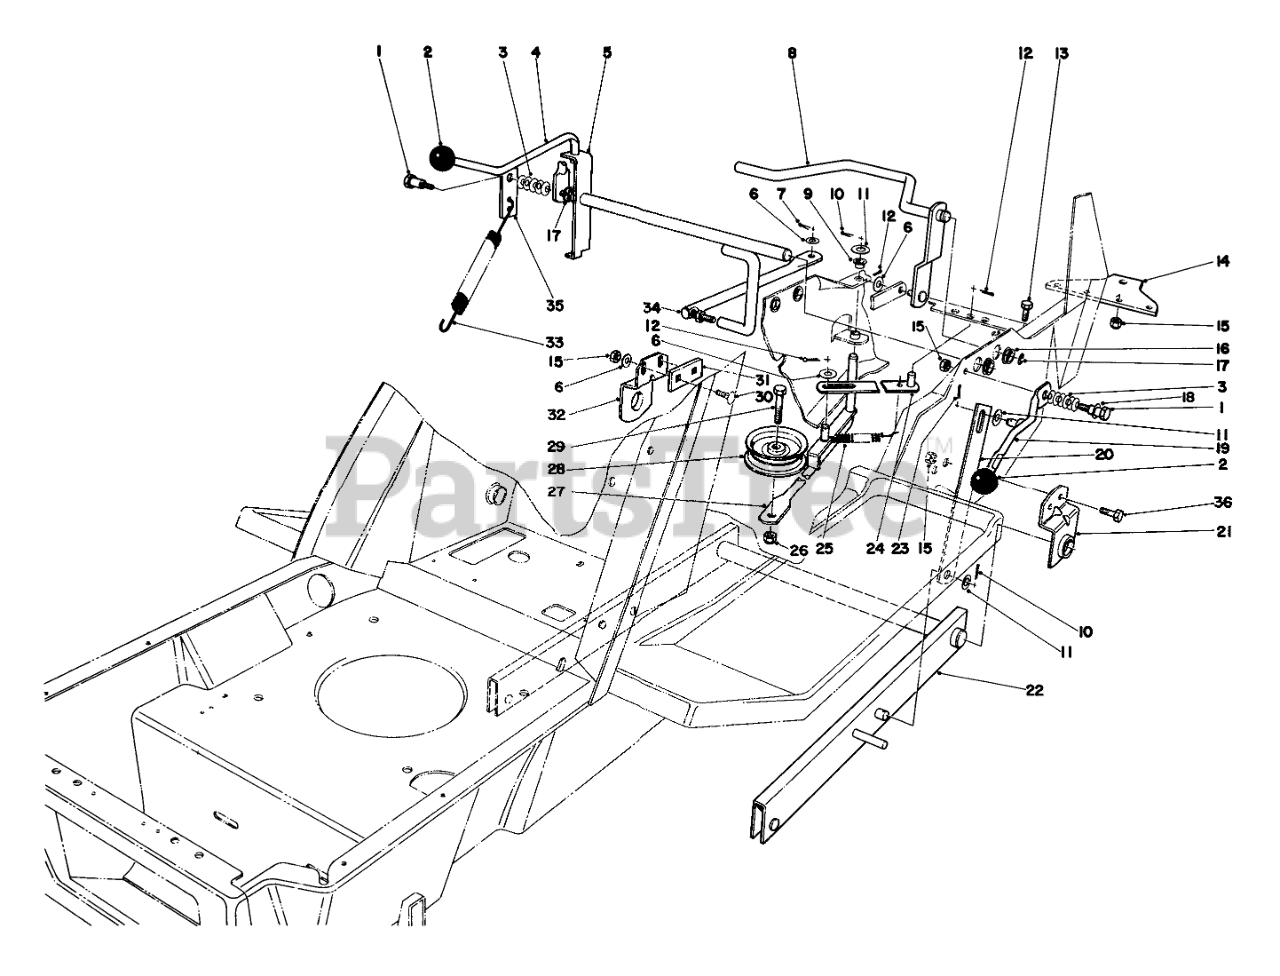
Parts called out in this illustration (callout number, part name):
1	BOLT-SHOULDER
3	WASHER-BELLEVILLE
4	SHIFT LEVER BO
5	Shim Lever
6	WASHER-PLAIN
7	PIN-COTTER
8	CLUTCH ACTUATOR WA B
9	BUSHING-NYLINER
10	PIN-COTTER
11	WASHER-FLAT
12	PIN-COTTER
13	SCREW-HHF
14	HITCH PLATE R
15	NUT-LOCK, CONE
16	Nyliner
17	E-RING
18	WASHER-FLAT
19	HOC HANDLE WA B
20	H.O.C. STRAP B
21	LH PIVOT BAR RET B
22	Bar-Pivot
23	PIN-COTTER
24	SPRING RET WA B
25	DECK TENSION SPRNG O
26	NUT-LOCK, CONE
27	IDLER ARM WA BO
28	IDLER PULLEY
29	SCREW-HH
30	BOLT-CARR
31	SPACER
32	RH PIVOT BAR RET B
33	TRACTION SPRING
34	SHIFT ARM BO
35	BRKT-COBALANCE SPRING
36	SCREW-HH
